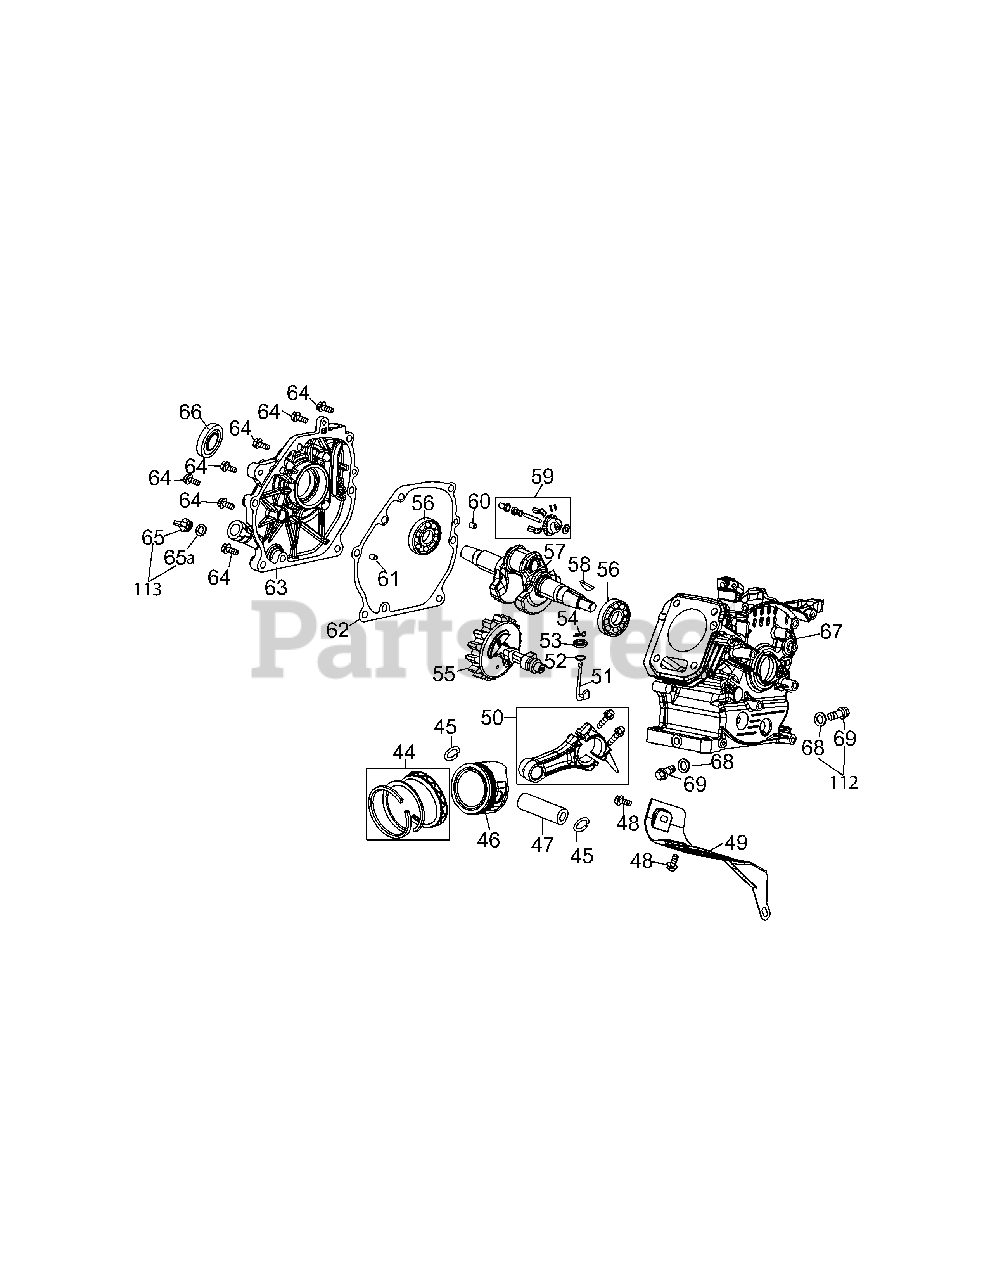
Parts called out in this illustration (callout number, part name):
44	Piston Ring Set
45	Piston Pin Snap Ring
47	Piston Pin
48	Bolt M6×12
49	Air Shield
50	Connecting Rod Assembly
51	Governor Arm Shaft
52	Washer 5.2×1.9
53	Governor Seal
54	Cotter Pin
55	Camshaft Assy.
56	Radial Ball Bearing, 6205
57	Crankshaft Assembly
58	Woodruff Key
59	Governor Gear/Shaft Assembly
60	Dowel Pin 7×14
61	Dowel Pin 9×14
62	Crankcase Cover Gasket
63	Cover Comp, Left Crankcase
64	Bolt M8×32
65	Oil Filler Plug Ass'y
66	Oil Seal, 25×41.25×6
67	Short Block
68	Washer 10×16×1.5
69	Oil Drain Plug
112	Oil Drain Plug & Washer Assembly
113	Oil Fill Plug Assembly
